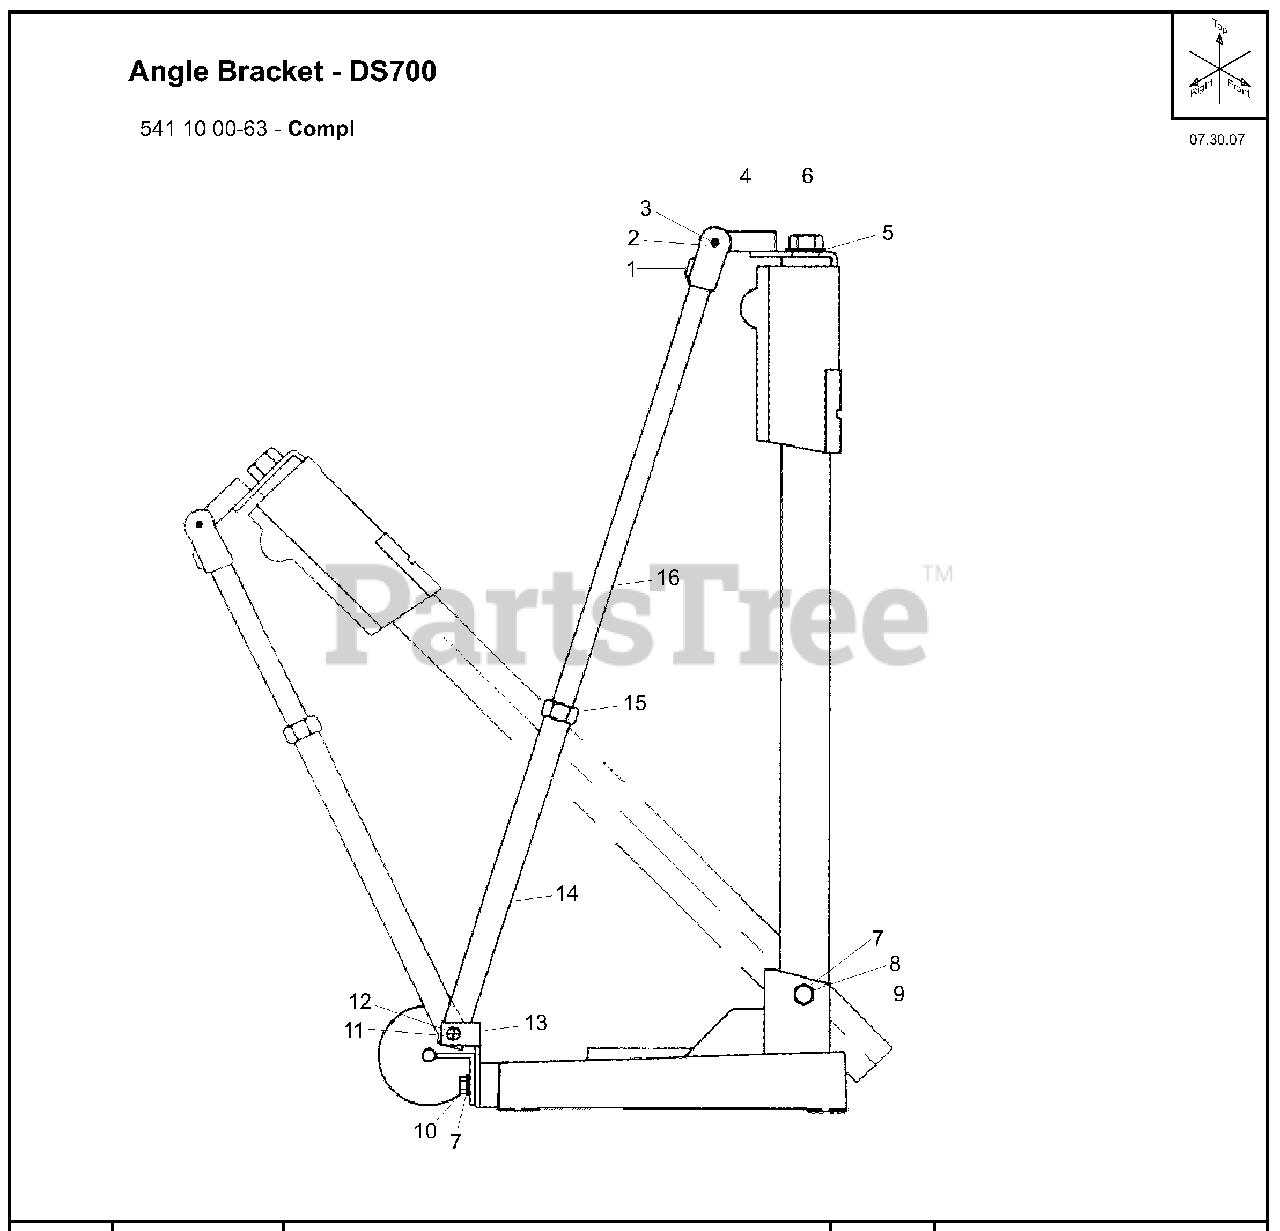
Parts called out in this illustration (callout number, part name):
1	Adapter, Upper Bracket Rod
2	Capscrew, Hex Hd, 3/8-16 x 1-1/2
3	Locknut, Fiber 3/8-16
4	Bracket, Upper Backstay
5	Washer, Flat 1" SAE
6	Capscrew, Hex Hd, 1" - 8 x 1-1/4
7	Washer, Flat 1/2 SAE
8	Capscrew, Hex Hd, 1/2-13 x 4-1/2
9	Locknut, 1/2-13 Flexloc
10	Capscrew, Hex Hd, 1/2-13 x 1-1/4
11	Capscrew, Hex Hd, 5/8-11 x 2-1/2
12	Locknut, 5/8-11 Thin Flexloc
13	Bracket, Lower Backstay
14	Backstay, Lower
15	Nut, Jam - Backstay
16	Backstay, Upper
